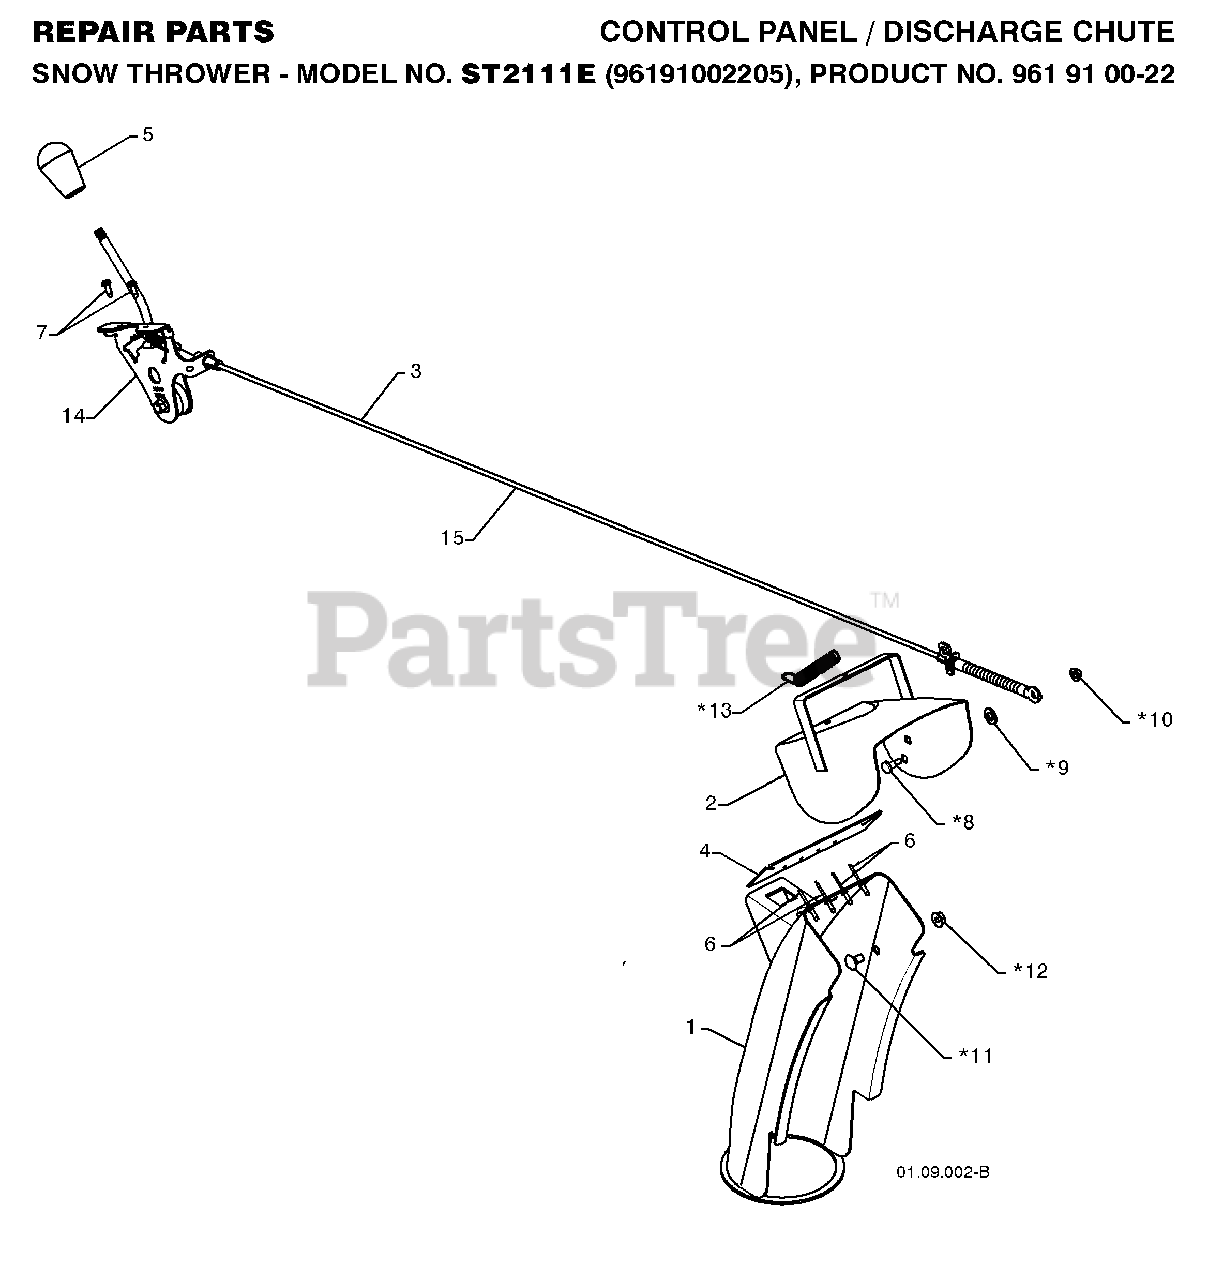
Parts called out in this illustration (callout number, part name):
3	CONTROL.ASM.DEFLECTOR
4	SEAL.DEFLECTOR
5	KNOB LEVER, BLACK
6	RIVET BLIND
7	SCREW #10-24 X 5/8
8	BOLT, SHOULDER
9	WASHER, NYLON FRICTION
10	NUT.HEX.FLANGE.1/4
11	BOLT
12	NUT, LOCK 5/16-18
14	CHUTE.DEFLECTOR.HEAD.SERVICE.
15	SERVICE.CHUTE.DEF.CBL.BLK
